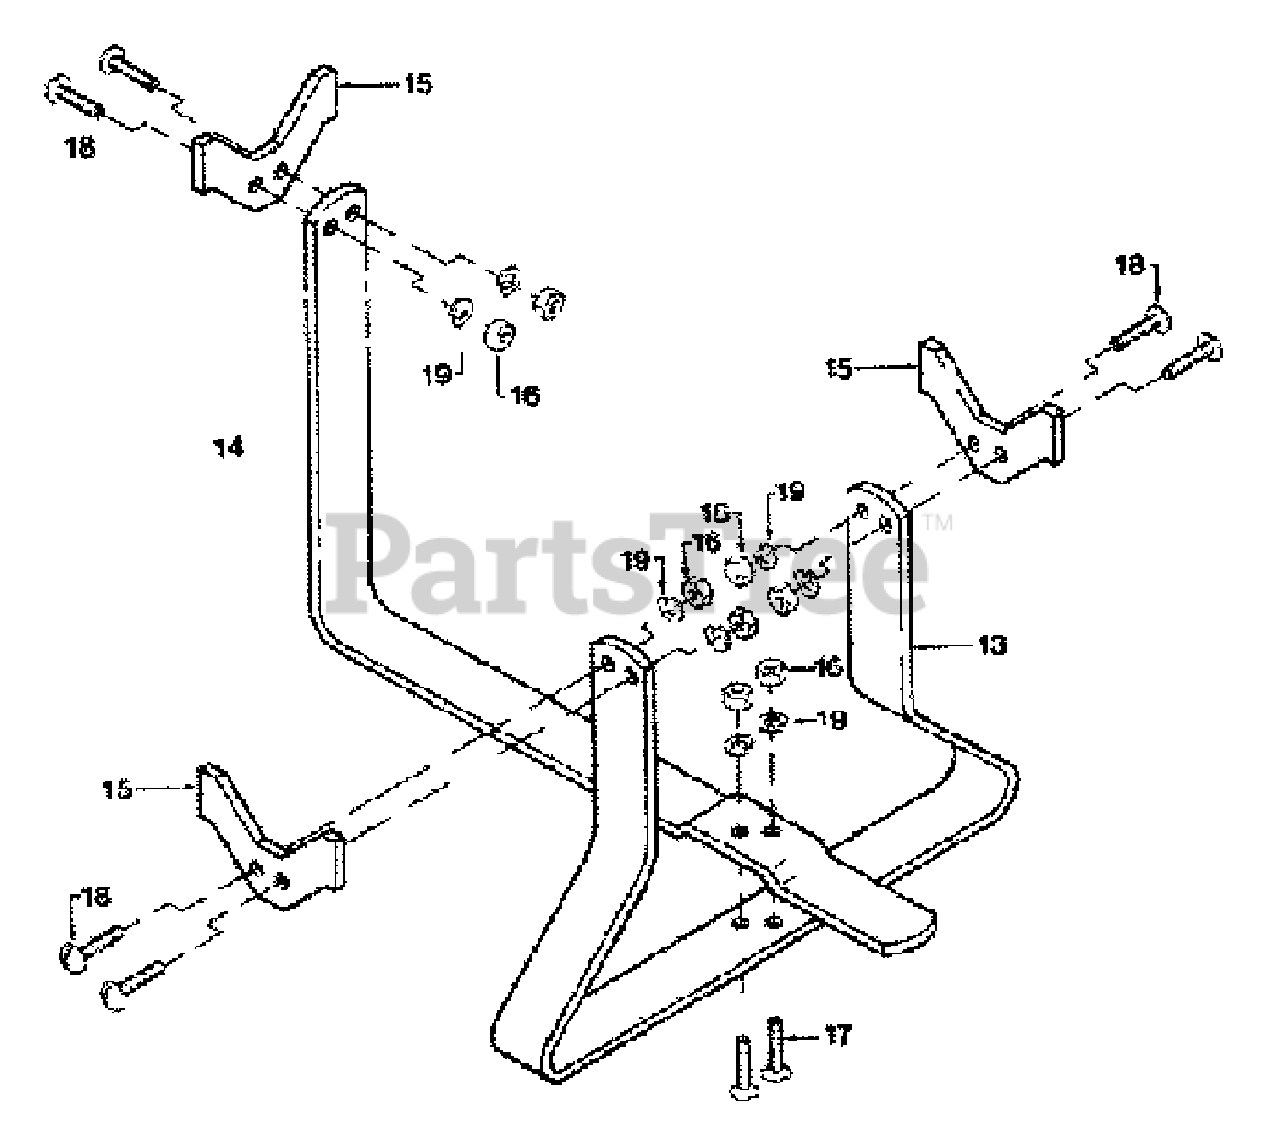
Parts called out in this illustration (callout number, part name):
13	Rear Cradle Support
14	Front Cradle Support
15	Tine Cradle Plate
16	Nut-hex, 1/4-20
17	Screw-hex hd., 1/4-20 x 3/4"
18	Screw-Round-head, 1/4-20 x 3/4"
19	Lockwasher-spring lock, 1/4"
